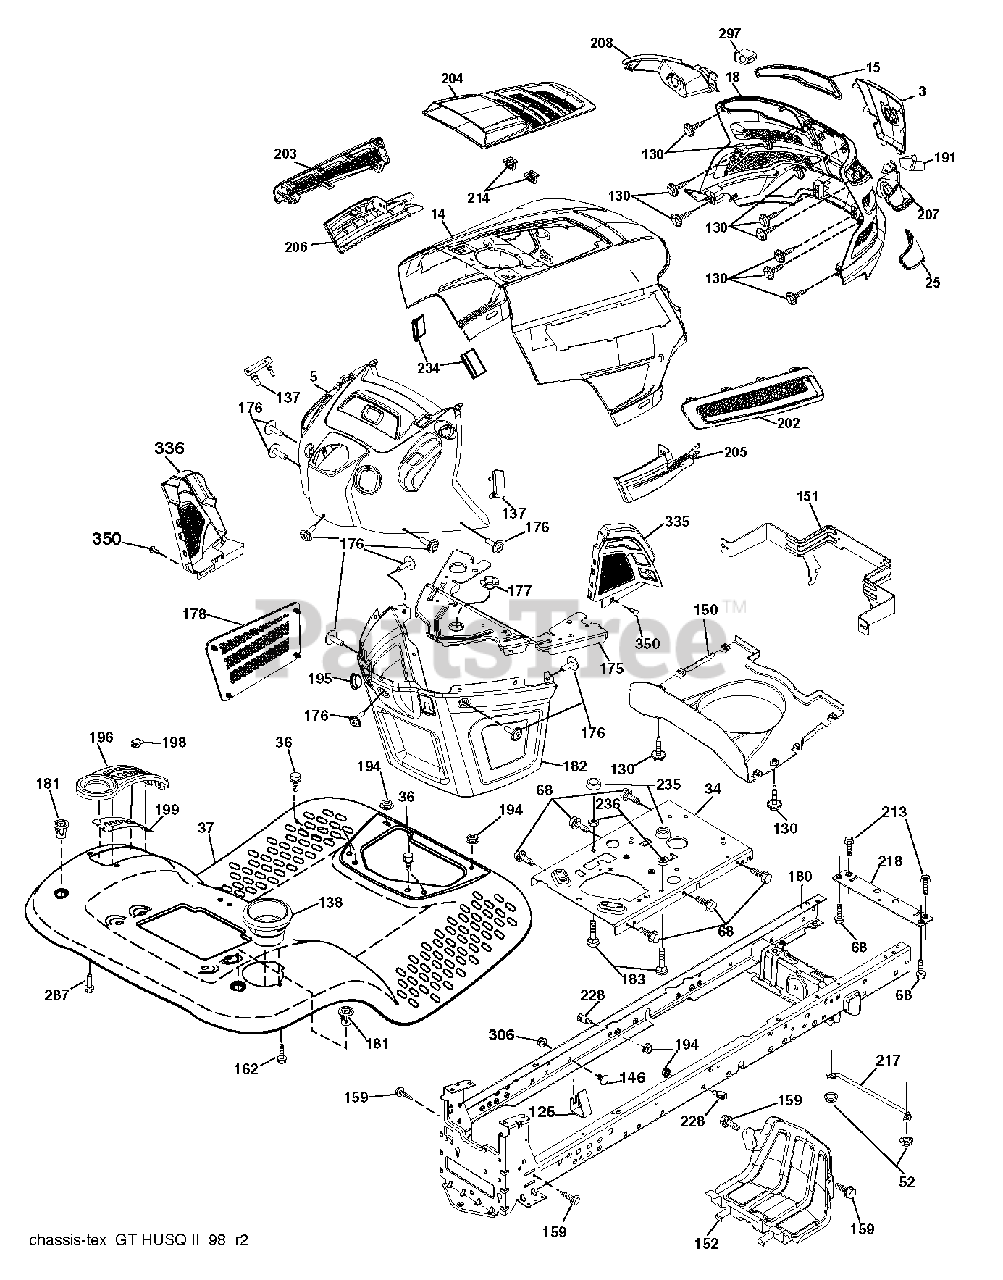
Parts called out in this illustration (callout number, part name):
3	APPLIQUE.SUBASM.GT.HUSQ.II
5	DASH.UPPER.ASSY.GT2.GREY
14	HOOD.ASM.HUSQVARNA.GT.TEX.ORAN
15	LENS.HEADLIGHT.LH.GTII.2011
18	GRILLE.SUBSTRATE.2011.
25	LENS.HEADLIGHT.RH.GTII.2011
34	PLATE.ENGINE.WELDED.CHASSIS
36	SCREW 5/16"
37	FENDER.TLT.PDL.CNTRL.W/CPH.ORG
52	LOCKNUT
68	SCREW LT
125	CLIP.FUEL.LINE
130	SCREW.#10 X 0.750.BOS
137	BUMPER DASH
138	HOLDER.CUP.LT.GREY
146	BOLT.RDHD.SHT.SQNK.3/8-16X5/8
150	AIR.DUCT.GTV.BLACK
151	BRACKET.PIVOT.HOOD.GT.HUSQ.II
152	SHIELD.BROWNING.PNT.GT.V2
159	SCREW, 3/8-16X3/4
162	SCREW.HI-LO.CONSOLE
175	PLATE.CROSSMEMBER.HUSQ
176	SCREW.#10-24X5/8.RN.QU
177	BUSHING, STEERING
178	CARGO.ASM.NET.TXGT.W/C
180	CHASSIS
181	BUSHING.MNT.FEND.CRGO.TEX.49
182	DASH.LOWER.COMMON.12V.ADAPTOR
183	BOLT.5/16-18X1-1/4 FULL THD
191	INSERT.REFLECTIVE.RH.HUSQ.GTII
194	NUT LOCK HEX FLANGE 5/16-18
195	PLUG.HOLE.DASH.LOWER.12V.BLK
196	DECKLFT.CONSOL FULL ASSM GREY
198	INDICATOR.DECK.LIFT.RED
199	PLATE.DECK.LIFT.HUSQ.LT
202	VENT.SIDE.RH.GT.HUSQ.II.
203	VENT.SIDE.LH.GT.HUSQ.II.498
204	VENT.TOP.HUSQ.GT2
205	SIDE.TRIM.RH.GT.HUSQ.II
206	SIDE.TRIM.LH.GT.HUSQ.II.GRAY
207	BEZEL LIGHT.RH.GT.II.MYLAR
208	BEZEL LIGHT.LH.GT.II.MYLAR
213	BOLT
214	CLIP.RETAINER.TINNER.
217	ROD.PIVOT.HOOD
218	X-PIECE.HOOD.STOP.NON/
228	STUD.FASTNER.W/ANTI-ROTATE
234	BUMPER.HOOD.TEX.HUSQVARNA
235	SPACER FENDER
236	NUT.CENTERLOCK.5/16-
287	SCREW 1/4X20
297	INSERT.REFLECTIVE.LH.HUSQ.GTII
306	NUT LOCK FLG 3/8-16 UNC
335	COVER.LOWER.DASH.RH.BLACK
336	COVER-LH.LOWER.DASH.GT2.BLACK
350	CLIP.X-MAS.TREE
